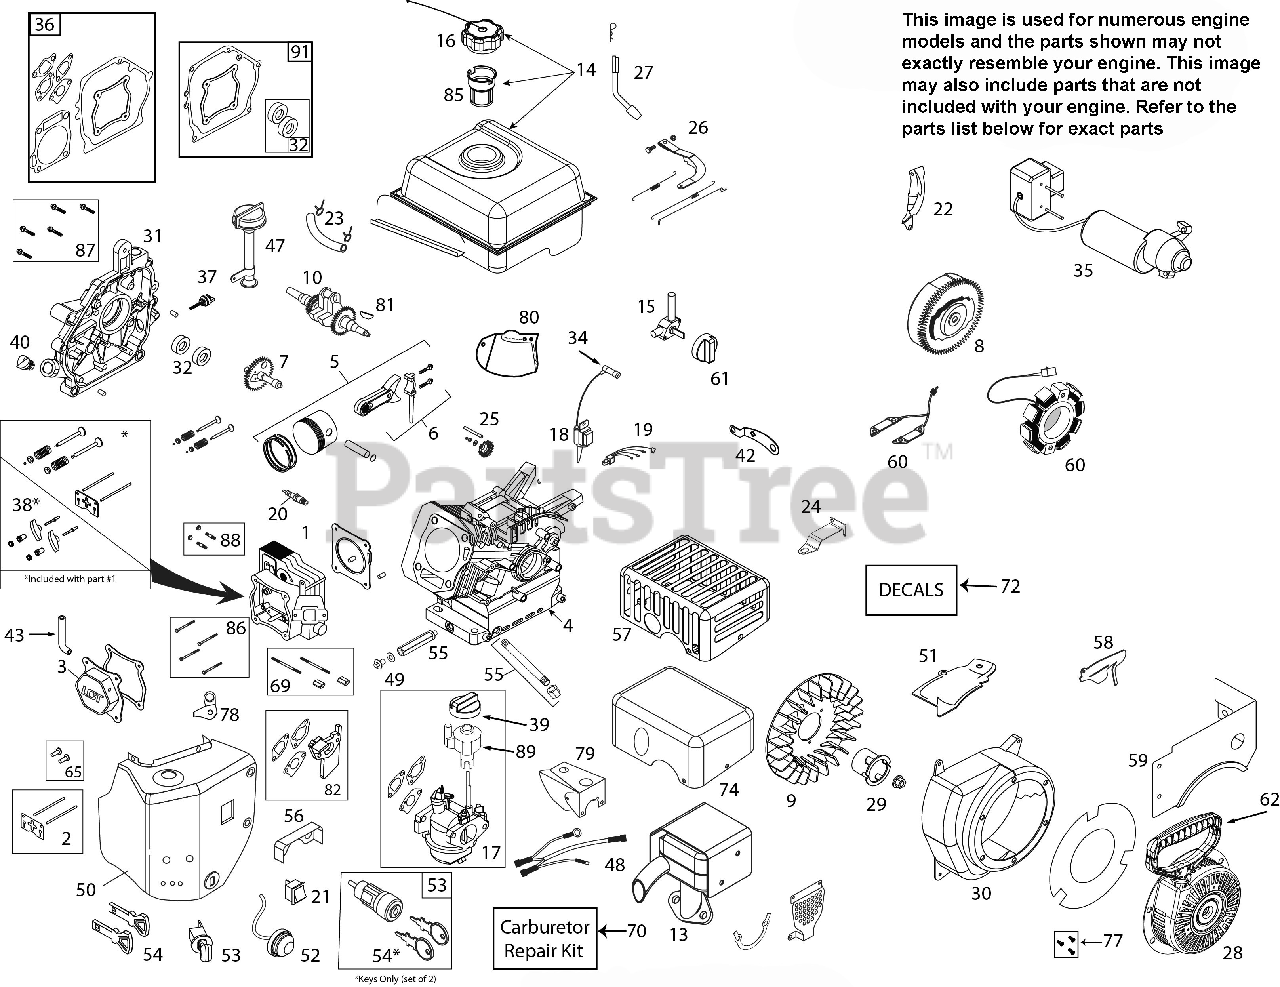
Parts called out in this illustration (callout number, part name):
1	CYLINDER HEAD ASSY(W/GASKET)
2	PUSH ROD & PLATE KIT (W/GSKT)
3	VALVE COVER (W/GASKET)
4	CYLINDER (FRONT OIL DRAIN)
5	PISTON & ROD ASSEMBLY
7	CAMSHAFT - MCR (W/GASKET)
8	FLYWHEEL - ELECTRIC START
9	COOLING FAN - FLYWHEEL
10	CRANKSHAFT (#17 KEYED)
13	MUFFLER ASSEMBLY
14	FUEL TANK ASM (MATTE BLACK)
15	FUEL TANK ON/OFF VALVE
16	CAP, FUEL TANK BLACK
17	CARBURETOR W/IDL DN-CTRL-GSKTS
18	IGNITION COIL (CDI) (STANDARD)
20	SPARK PLUG - PLATINUM
21	ON/OFF SWITCH - ROCKER (RED)
22	SHIELD - FLYWHEEL (ELECTRIC)
23	FUEL HOSE KIT 1/4-230MMW/CLMPS
24	SPEED CONTROL BRACKET (FIXED)
25	GOVERNOR GEAR ASSEMBLY
26	GOVERNOR ARM & LINK KIT
27	GOVERNOR ARM PADDLE
28	RECOIL STARTER ASSY RND-BLACK
29	STARTER CUP RND STYLE STARTER
30	BLOWER HOUSING (GLS BLACK)
31	CRANKCASE COVER
32	OIL SEAL KIT (2 PCS)
34	SPARK PLUG BOOT (W/MTL SHIELD)
35	120V ELECTRIC STARTER
36	ENGINE GASKET KIT
38	ROCKER ARM KIT (W/GASKET)
39	CHOKE CONTROL KNOB (RED)
40	NON-REMOVABLE PLASTIC PLUG
43	BREATHER TUBE
47	HIGH OIL-FILL TUBE/DIPSTICK
48	WIRE HARNESS
49	OIL DRAIN PLUG (W/WASHER)
50	HEATER BOX, MATTE BLACK, 254CC
52	PRIMER BULB WITH HOSE-SNOW (RED)
53	KEY SWITCH, STOP-RUN (W/KEYS)
54	KEY, TURN LCT (2/PACKAGE)
55	FRONT OIL DRN PIPE & NUT ASSY
56	CARBURETOR VAPOR SHIELD
57	CE COMPLIANT MUFFLER SHIELD
58	SHIELD - GOVERNOR LINKAGE
59	FUEL TANK SKIRT (MATTE BLACK)
60	CHARGING COIL (60-WATT AC)
61	FUEL CONTROL KNOB (RED)
62	STARTER GRIP-SNOW (DELUXE)
65	TAPPET KIT (SET OF 2)
69	CARBURETOR STUDS & COUPLNG KIT
70	CARBURETOR REPAIR KIT
72	LABEL KIT (2016) 208-254
74	MUFFLER HEAT SHIELD COVER
77	RECOIL BOLT KIT
79	CARBURETOR COVER
80	SHIELD GOVERNOR LINK
81	WOODRUFF FLYWHEEL KEY 5-PACK
82	CARBURETOR SPACER
85	FUEL TANK STRAINER
86	HEAD BLT KIT 136-179-208-254CC
87	CC COVER BLT KIT 179-208-254CC
88	MUFFLER MTG STUD KIT
89	SPEED CONTROL KNOB
91	CRANKCASE GASKET KIT(254-GEN2)
9999	HIGH ALT JET - 254CC L15 CARB
